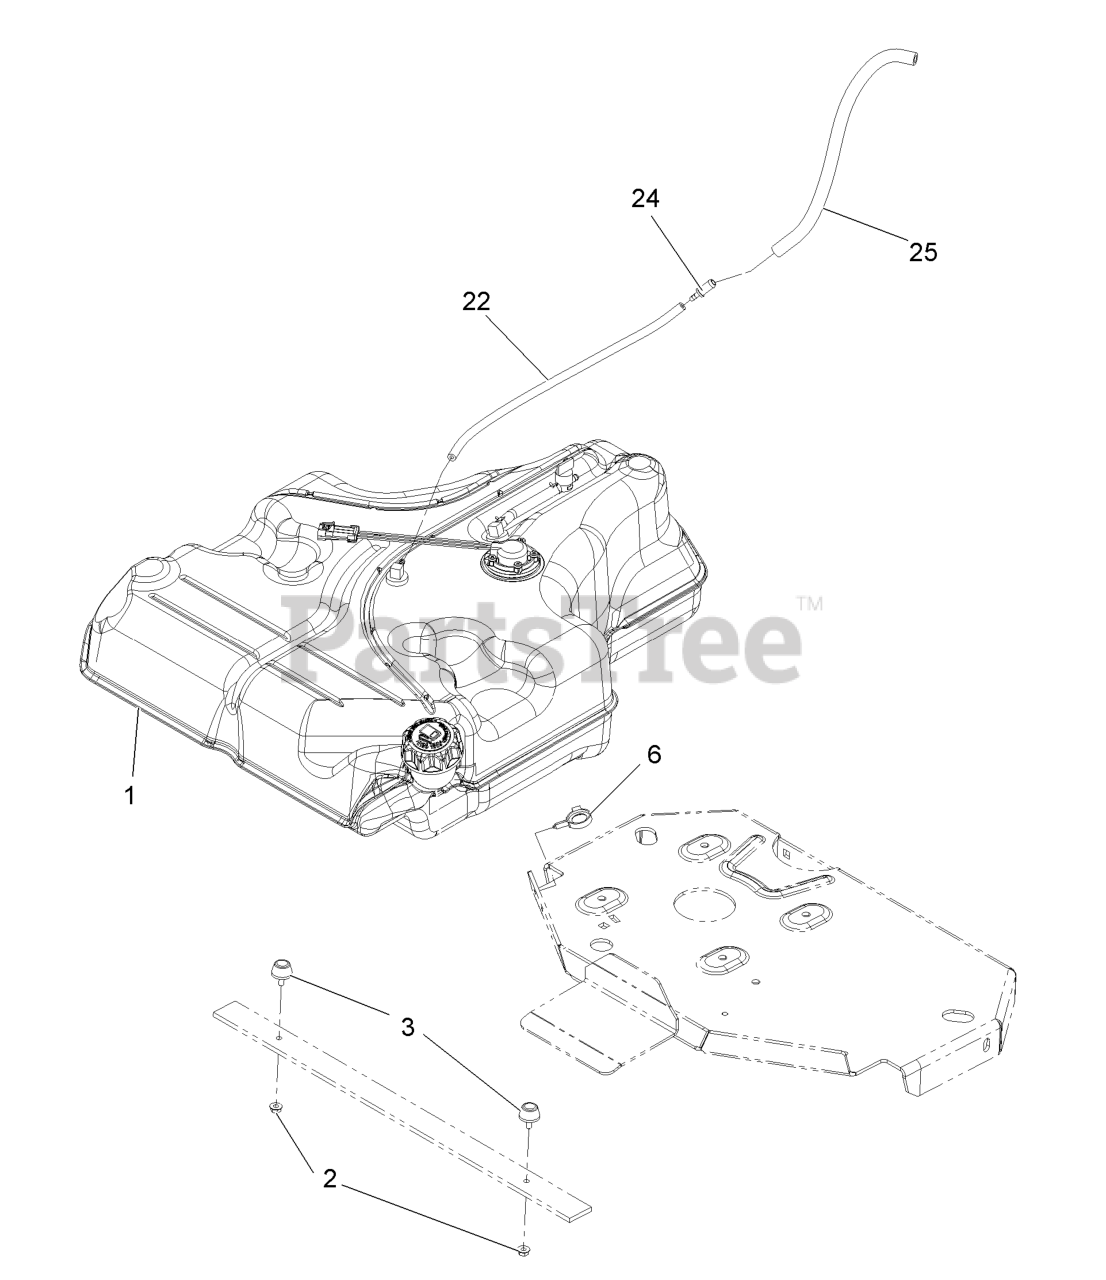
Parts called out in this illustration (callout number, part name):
3	BUMPER-RUBBER
6	CLAMP-HOSE
22	HOSE-FUEL
24	FITTING-STRAIGHT
25	HOSE-FUEL
